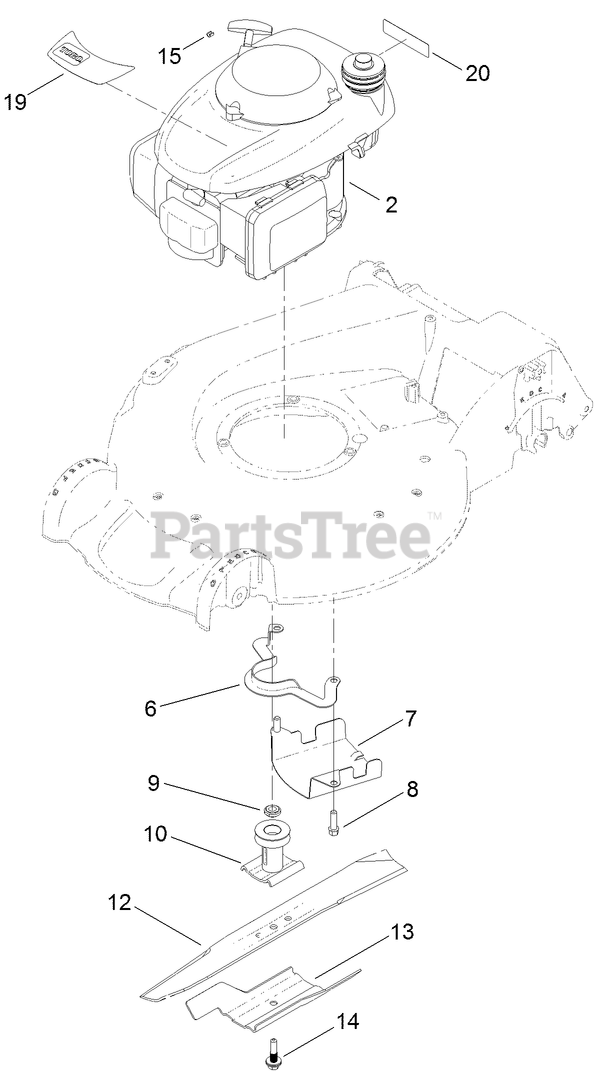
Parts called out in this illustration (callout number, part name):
6	GUIDE-BELT
7	SHIELD-GRASS
8	SCREW-TAPTITE
9	SPACER-DRIVER
10	DRIVER-BLADE
13	ACCELERATOR-BLADE
14	BOLT-BLADE
15	STOP-ROPE
19	DECAL-ENGINE
20	DECAL-ARRESTER, SPARK
